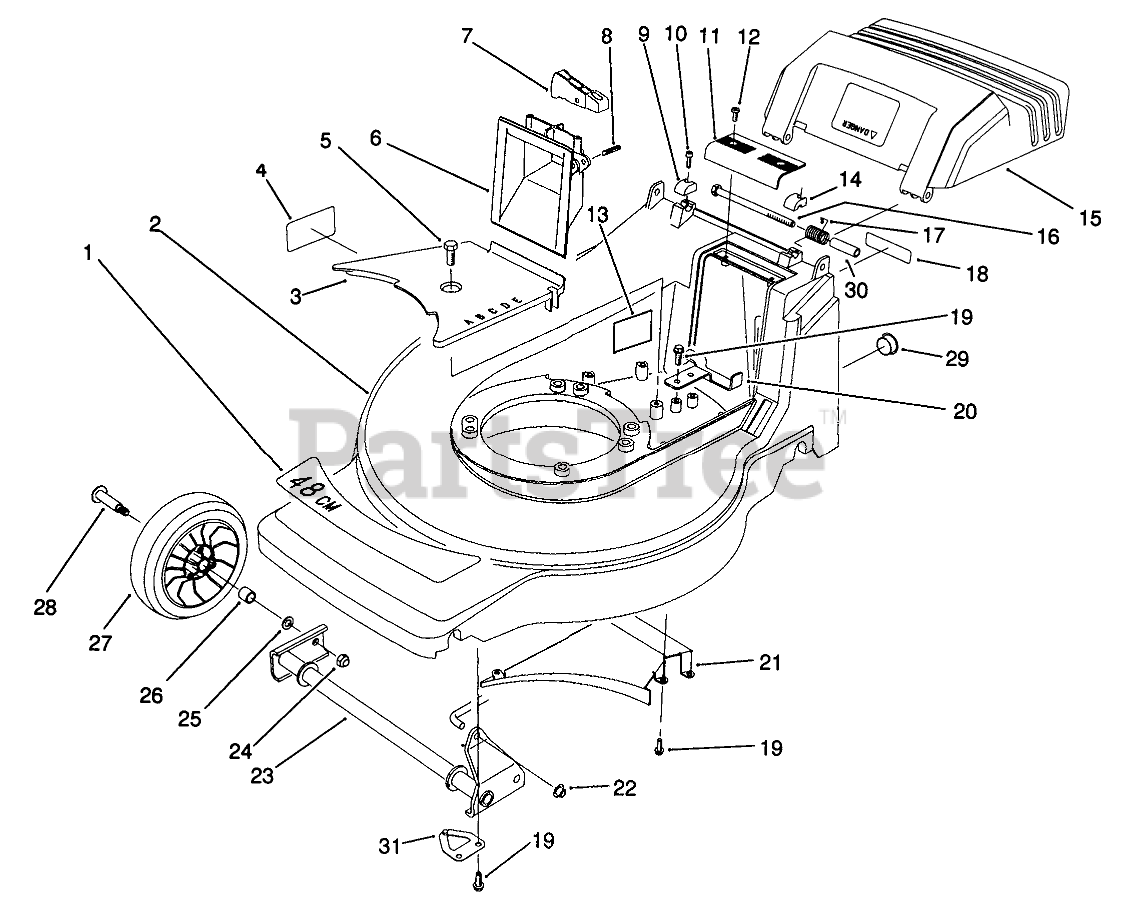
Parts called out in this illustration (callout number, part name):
1	DECAL - DECK
2	Housing-48cm (Incl. Ref. #1, 4, & 13)
3	BELT COVER
4	Decal Danger
5	SCREW-HWHTF
6	GRIP - LOWER
7	TRIGGER - HOC
8	PIN-SPIRAL
9	CAP-HINGE BOLT, RH
10	SCREW-HSH
11	GRIP-UPPER
12	SCREW-PPH, PLASTITE
13	Decal-Noise
14	CAP-HINGE BOLT, LH
15	Door-Discharge
16	SCREW-HH
17	DOOR SPRING
18	DECAL FRENCH REGUL.
19	SCREW-HWH
20	REAR BELT GUIDE
21	Ramp-Discharge
22	NUT-PUSH
23	FRONT PIVOT WA
24	Nut
25	WASHER
26	BUSHING
27	Wheel & Tire Assembly (Incl. Ref. #26)
28	BOLT-WHEEL
29	DOME PLUG (DP-1000)
30	SPACER-DOOR
31	LH AXLE RETAINER
